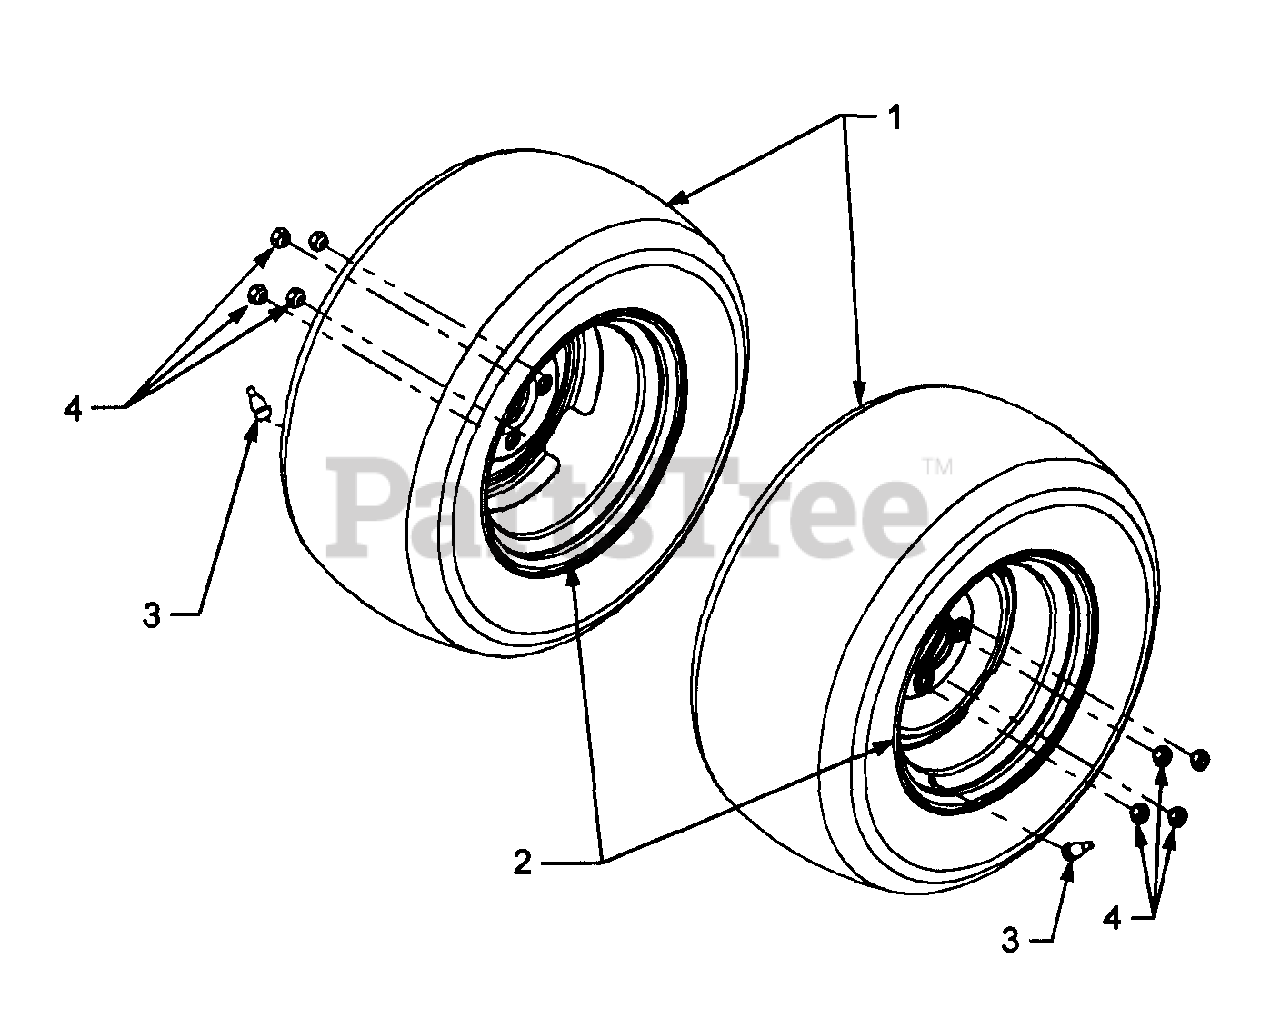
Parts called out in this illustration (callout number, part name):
1	Tire, Turf, 23 x 10.5 - 12
2	Rim Assembly, Wheel
3	Valve, Tubeless Air
4	Lug Nut, 7/16-14
